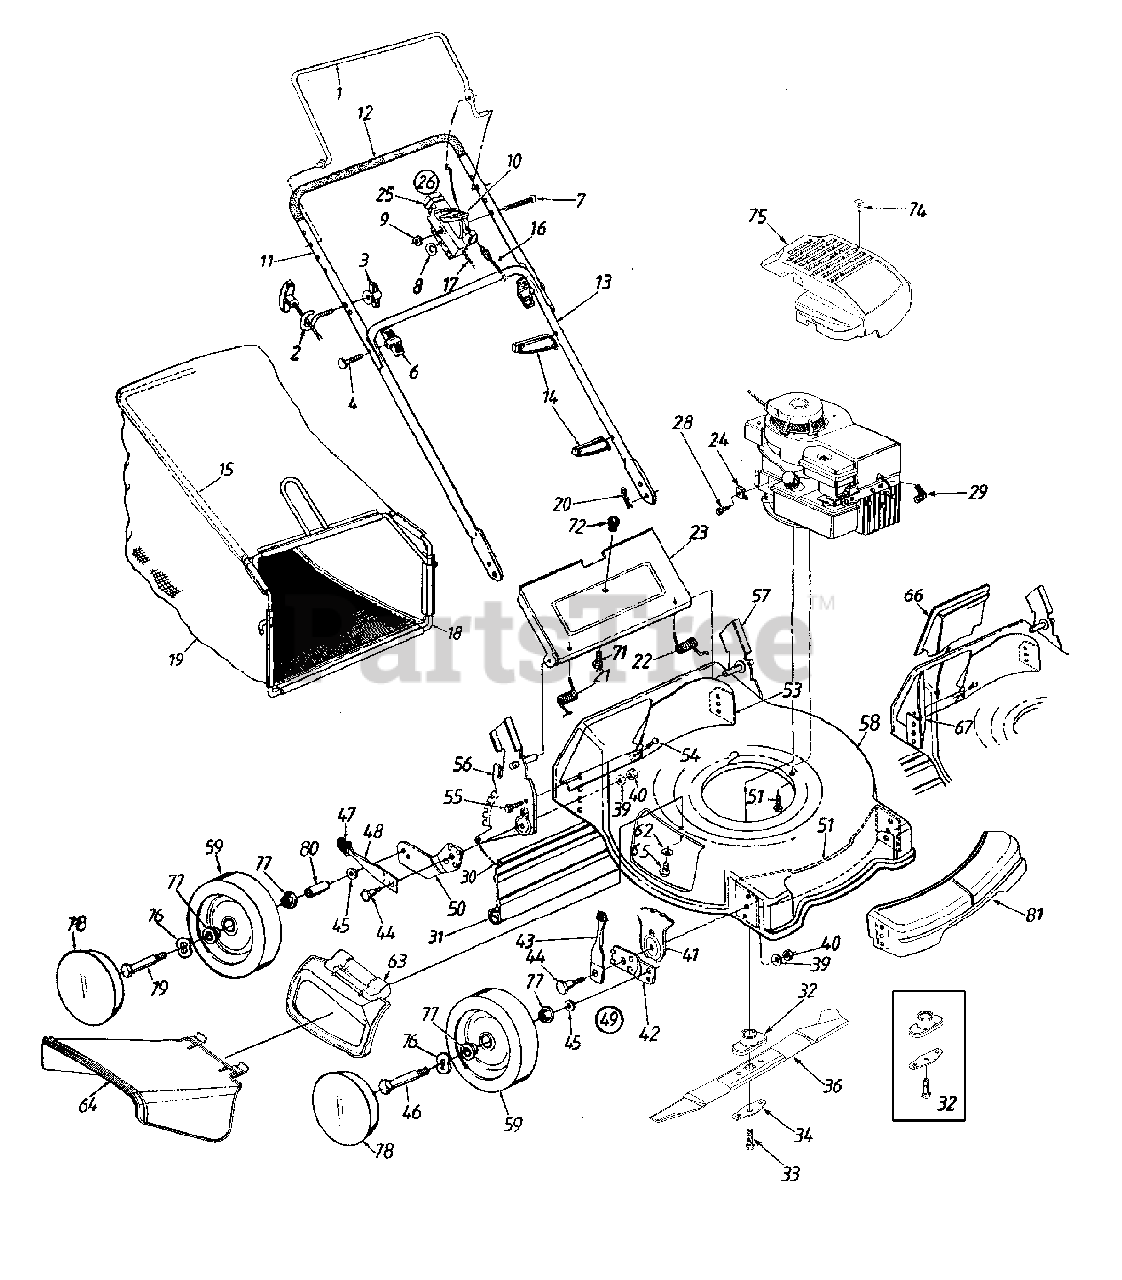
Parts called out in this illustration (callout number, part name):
1	Control Handle Assembly
2	Rope Guide
3	Handle Knob 1/4-20 Thd.
4	Curved Hd. Bolt 5/16-18 x 2"
6	Hand Knob
7	Oval C-Sunk Mach. Scr.
8	Spring Washer
9	Hex Lock Nut
10	Throttle Lever
14	Cable Tie
16	Control Cable
17	Throttle Control Wire
20	Internal Cotter Pin
21	Door Spring-R.H.
22	Door Spring-L.H.
25	Throttle Body
26	Throttle Box Comp.
28	Hex Washer Hd. Screw #10-32 x .62
29	Spark Plug Boot
30	Wire Rod
31	Rear Flap
32	Blade Adapter Kit
33	Hex Bolt 3/8-24 x 1.5"
34	Blade Bell Support
36	Mulching Blade 21"
39	Bell Washer
40	Hex Nut 3/8-16 Thd.
41	Height Adj. Plate
43	Spring Lever Ass'y w/Knob
44	Shoulder Bolt
45	Bell Washer .38" I.D. x .88"
46	Front Axle Bolt
47	Spring Lever Knob
48	Spring Lever
49	Height Adj. Assy-R.H.
50	Pivot Bar R.H.
54	Torx Mach. AB-Tap. Scr. 1/4 x .62"
55	Hex Lock Washer Hd. AB-Tap Scr.
59	Wheel Assembly Comp.
62	Bell Washer 1/4" I.D.
63	Hinged Mulching Plug
64	Chute Deflector: side discharge
65	Hex Hd. Self-Tap. Scr. 1/4-20 x .5
71	Truss Scr. #10-24 x .38
72	Knob: Chute Door
74	Hi-Lo Scr. #10 x 1.25
75	XTE Black Shroud
76	Wave Washer
77	Ball Bearings
78	Hub Cap: Radial Spoke Beige
79	Rear Axle Bolt
80	Spacer
81	Cover: Front Deck Black
